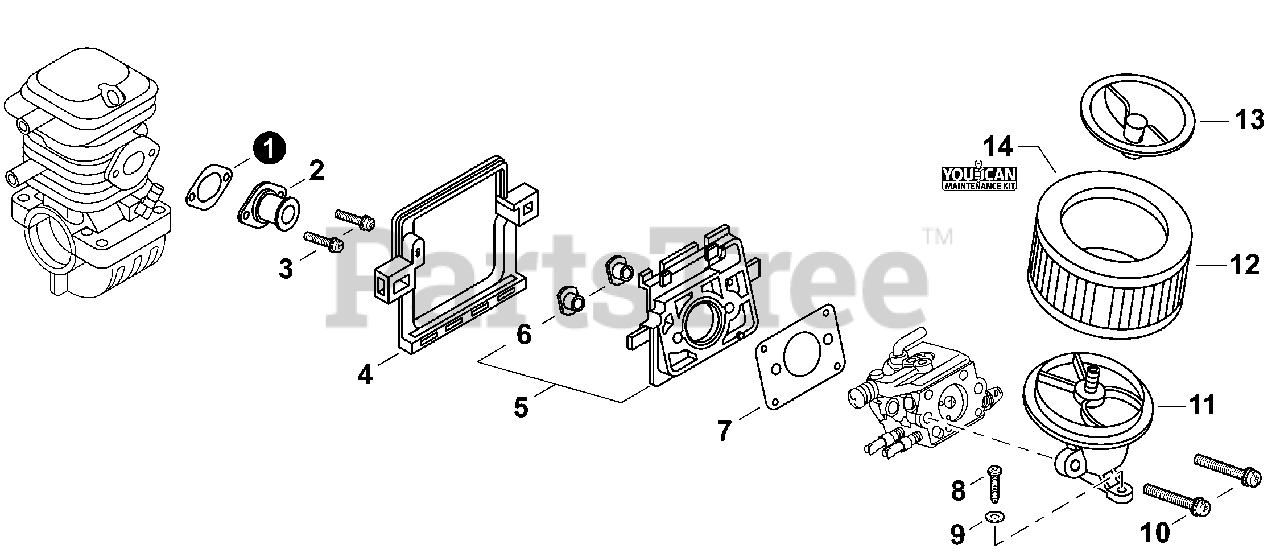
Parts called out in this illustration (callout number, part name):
1	GASKET, INTAKE
2	BELLOWS, INTAKE
3	SCREW 5×14
4	CUSHION
5	INSULATOR KIT, INTAKE
7	GASKET, INTAKE
8	SCREW, TAPPING 5×20
9	WASHER, FLAT 5.5×10×0.8
10	SCREW 5×50
11	ADAPTOR, INTAKE
12	FILTER, HEAVY-DUTY AIR
13	CAP, AIR FILTER
14	TUNE-UP KIT - YOUCANT
